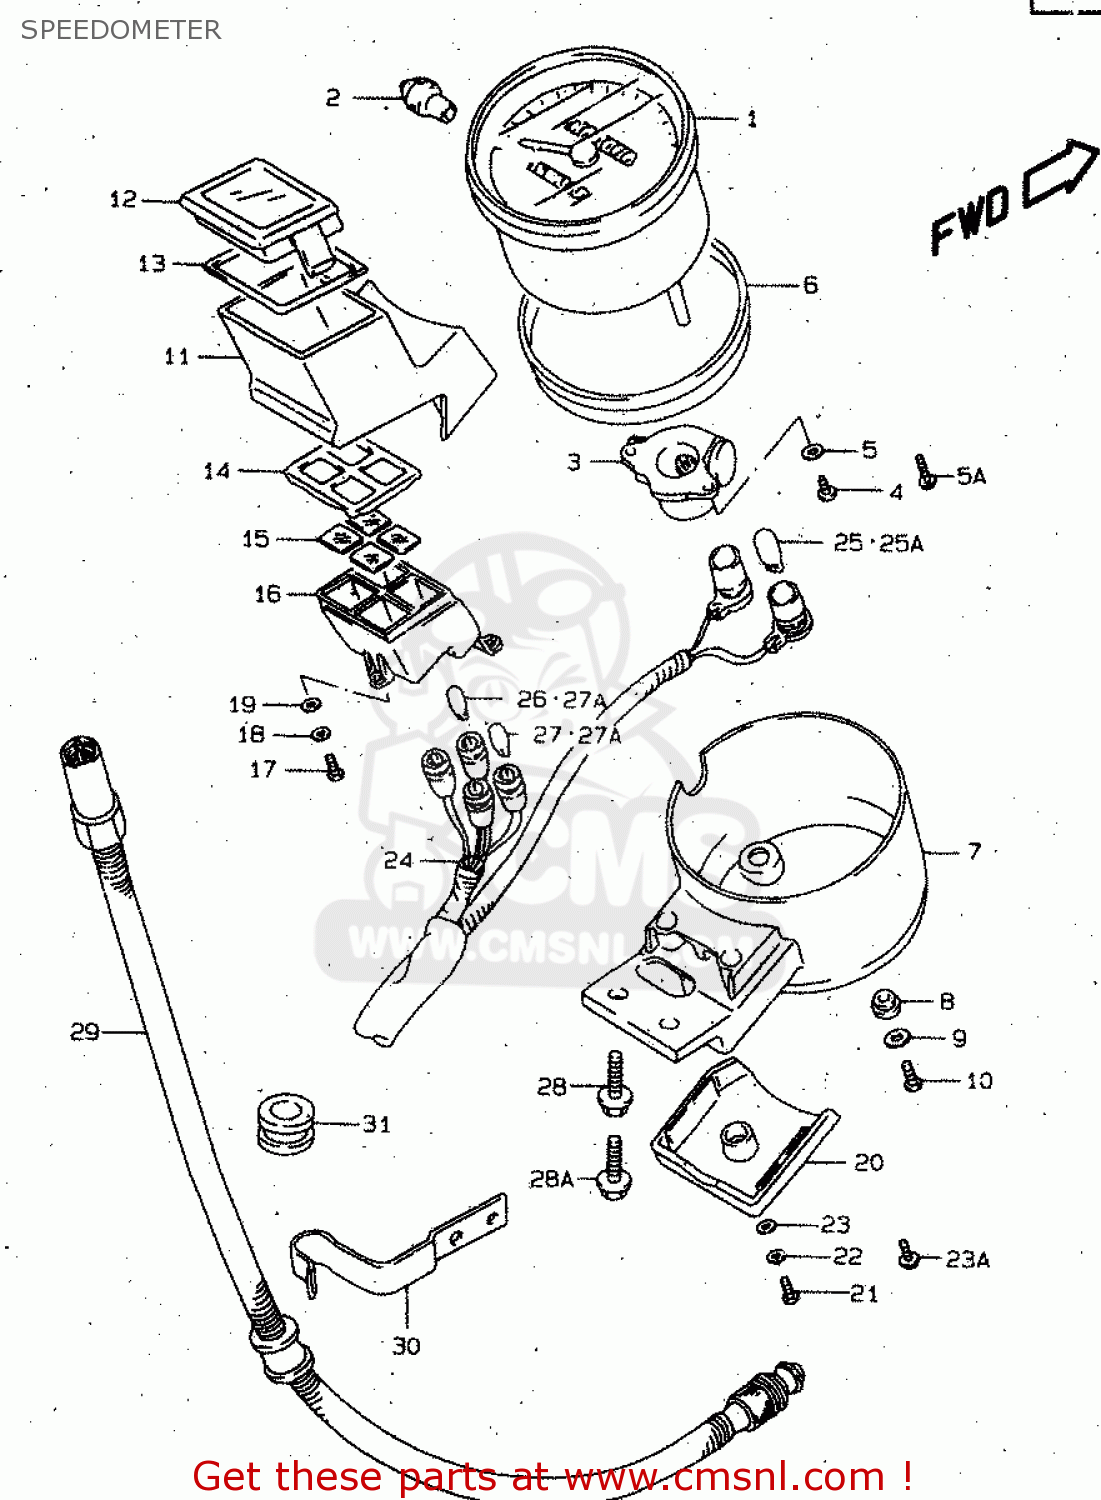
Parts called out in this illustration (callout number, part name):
1	SPEEDOMETER(KILO)
2	KNOB,TRIP
3	BOX,GEAR
4	SCREW
5	WASHER,LOCK
5A	SCREW
6	CUSHION
7	COVER,METER
8	CUSHION,METER
9	WASHER
10	SCREW
11	BOX,PILOT
12	LENS,PILOT BOX
13	CUSHION
14	PLATE,PILOT LENS
15	LENS SET
16	CASE,PILOT LAMP
17	SCREW
18	WASHER,LOCK
19	WASHER
20	COVER,PILOT BOX
21	SCREW
22	WASHER,LOCK
23	WASHER
23A	SCREW
24	SOCKET,METER
25	BULB(12V3.4W,T10)
25A	BULB(12V3.4W,T10)
26	BULB(12V3W,T6.5)
27	BULB(12V1.7W,T6.5)
27A	BULB(12V1.7W,T6.5)
28	BOLT
28A	SCREW
29	CABLE ASSEMBLY,SPEEDOMETER
30	GUIDE,SPEEDOMETER CABLE
31	GROMMET
